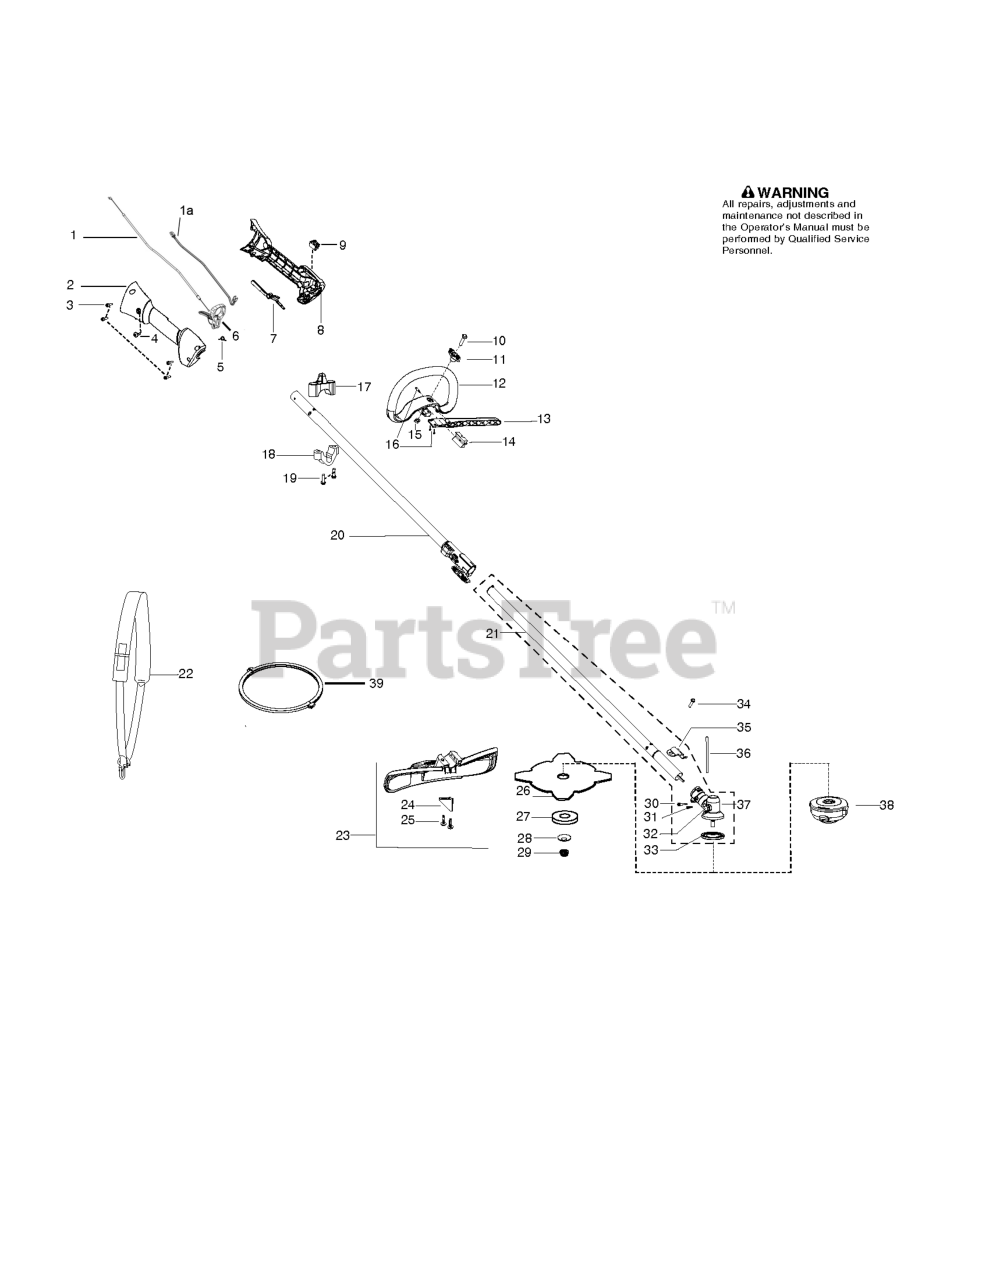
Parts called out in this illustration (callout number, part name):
1	ASSY THROTTLE
2	HSG THROTTLE RIGHT HVA
5	SPRING TRIGGER
6	TRIGGER THROTTLE HVA ORANGE
7	THROTTLE LOCKOUT HVA ORANGE
8	HSG THROTTLE LEFT HVA
9	SWITCH
10	SCREW M6X50
12	HANDLE LOOP
14	SPACER PLASTIC
16	SCREW IHSCFTO
17	CLAMP HARNESS UPPER
18	CLAMP HARNESS LOWER
20	KIT UPPER SPLIT BOOM
21	KIT LOWER SPLITBOOM
22	Harness - Diagonal with sign
23	KIT STRAIGHT SHIELD
24	Limiter - Line
25	SCREW 10-14X3/4 PLASTITE
26	Blade - Grass
27	SUPPORTING CUP
28	SUPPORT FLANGE
29	GEARHEAD NUT - BRUSHCUTTER
30	SCREW 8-32 X 16.51
31	SCREW 8-32 X 16.51 TT SC TRX
32	PLUG GREASE 9MM
33	DRIVE DISC
34	SCREW 1/4-20
35	BRACKET SHIELD STRAIGHT SHAFT
36	LOCKING PIN
37	ASSY GEARBOX
38	T25 TRIM HEAD 10MM LH
39	GUARD TRANSPORT
